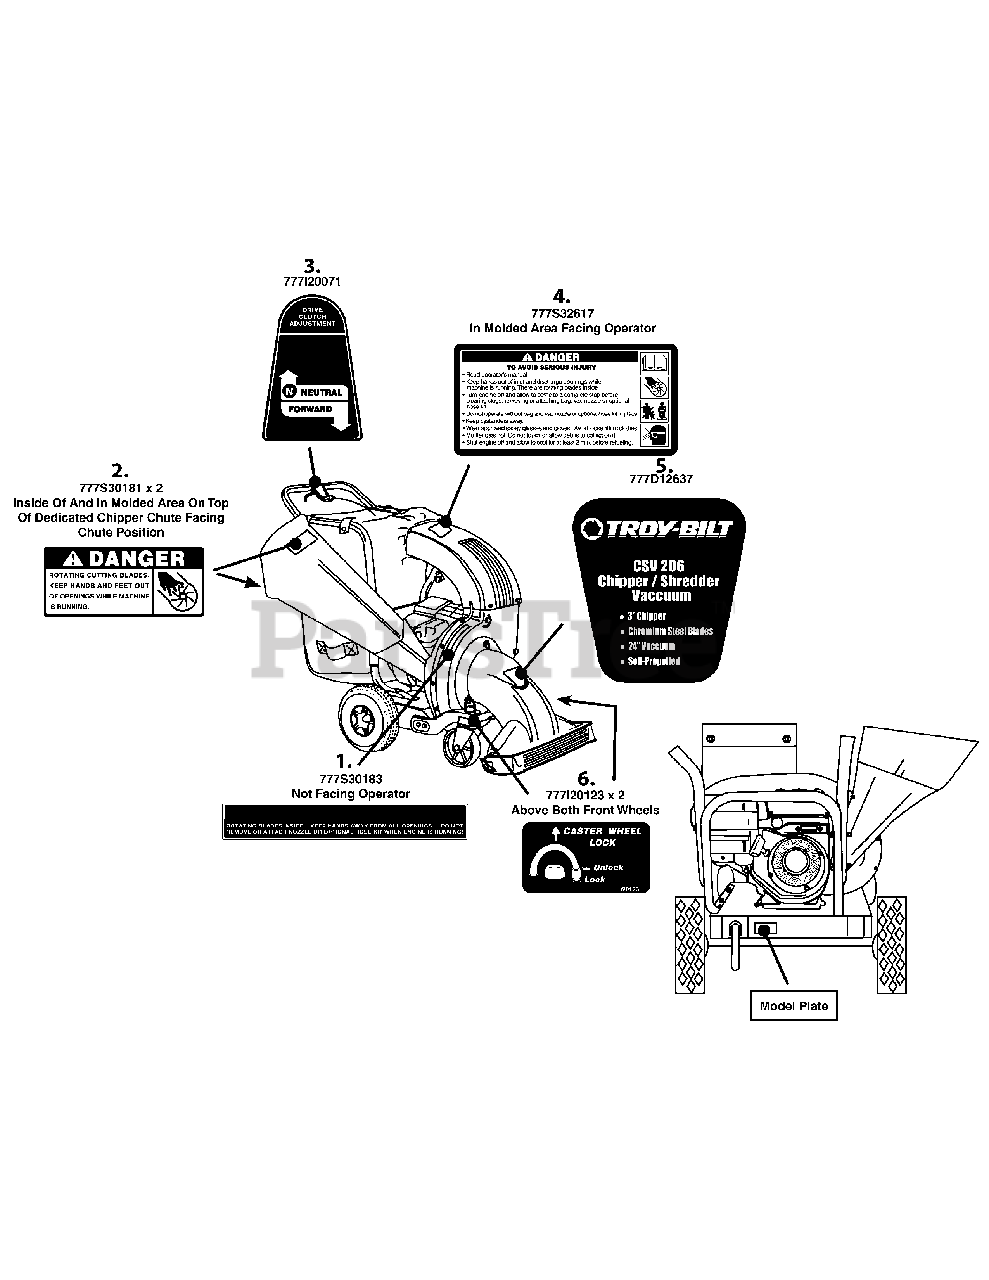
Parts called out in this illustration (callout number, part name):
1	LABEL-WARNING FLAIL
2	LABEL-TOP CHUTE DANGER
3	LABEL-SELF PROPELL
4	LABEL-CSV 020 WARNING
5	LABEL:CSV:FRONT NOZZEL:CSV206
6	LABEL-CASTOR WHL LK
